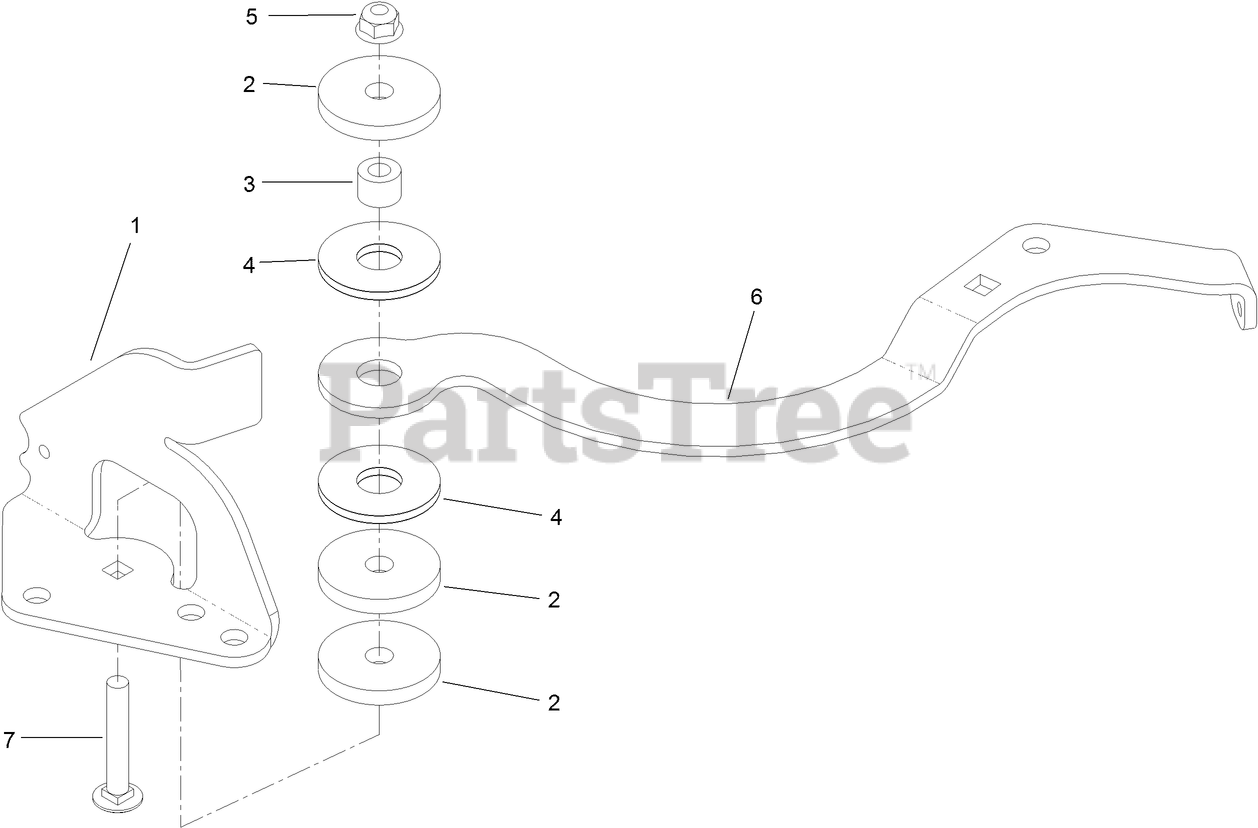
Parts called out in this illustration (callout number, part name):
1	MOUNT-IDLER
2	WASHER-PLAIN
3	BUSHING
4	WASHER-FRICTION, COMPOSITE
5	NUT-HF, NI
6	ARM-IDLER
7	BOLT-CARR
